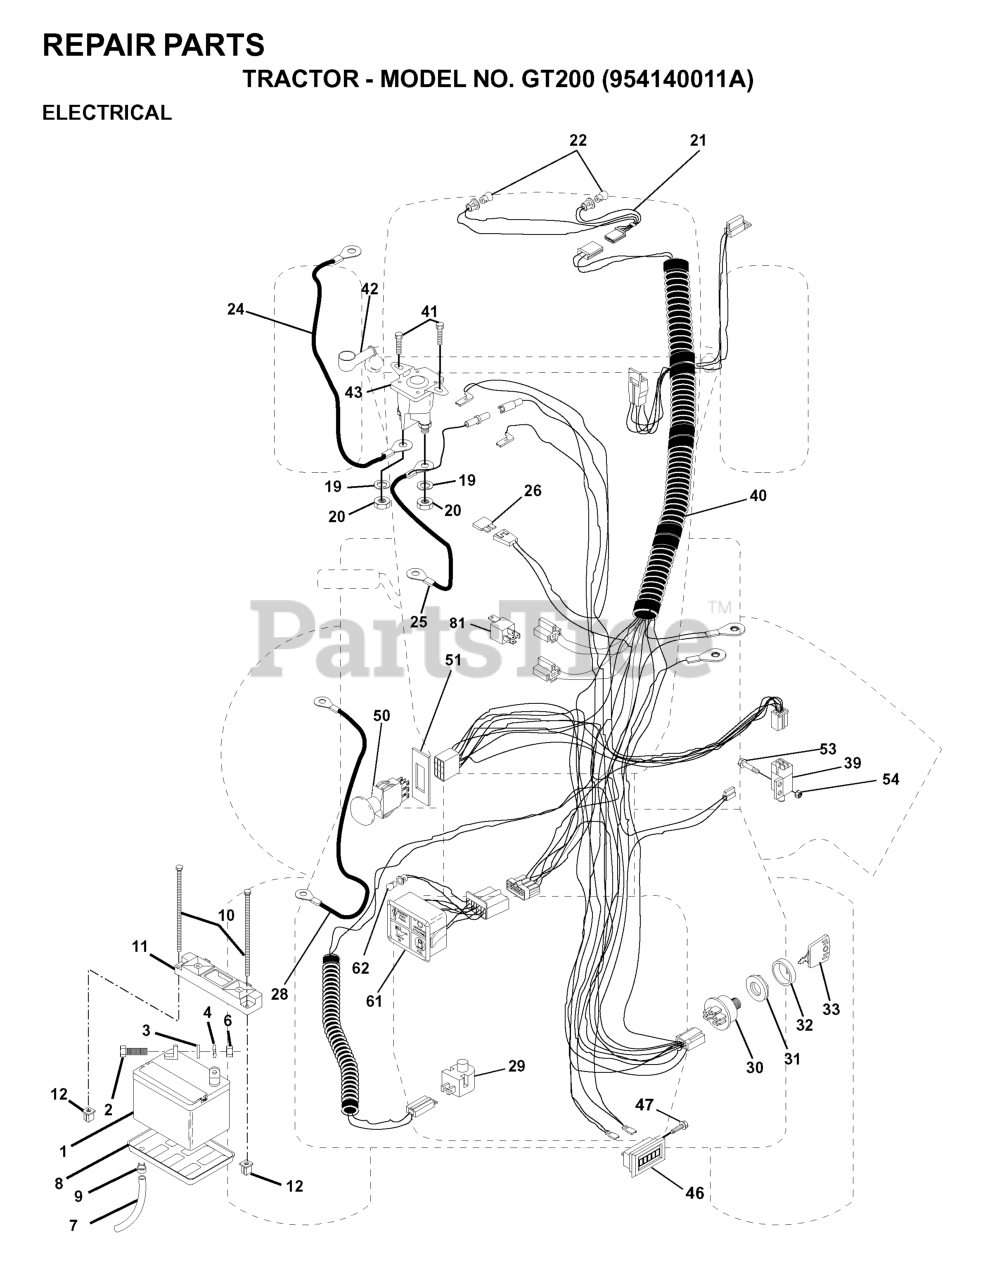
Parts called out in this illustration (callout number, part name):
1	BATTERY
2	BOLT.HEX.1/4.X.3/4.DICHROMATE
3	LOCKWASHER
6	NUT
7	PLASTIC TUBE
8	BATTERY TRAY T
9	HOSE CLAMP T
10	BOLT 1/4-20 X 7.5
11	BATTERY HOLDDOWN FRONT MOUNT
12	NUT, PUSH NYLON 1/4" BATTERY
19	LOCKWASHER
20	NUT
21	HARNESS LIGHT SOCKET
24	CABLE, STARTER
25	CABLE, BATTERY
28	CABLE, GROUND
29	RP.SWITCH.PLUNGER.NC.GRAY
30	SWITCH.IGNITION.4.POSITION
31	NUT IGNITION
32	COVER SWITCH KEY
33	KEY.MOLDED.GENERIC
39	SWITCH INTERLOCKT
40	HARNESS IGN.
41	SCREW
42	TERMINAL COVER
43	SOLINOID
46	HOUR METER T
47	Screw 10-24 x 1/2 Black
50	SWITCH PTO 3 PDT
51	FRAME RETAINING RING
53	SCREW **
54	Nut, Hex, Keps #10-32 UNF
61	LIGHT PACKAGE
62	BULB LIGHT T
81	RELAY.ASSY.T
